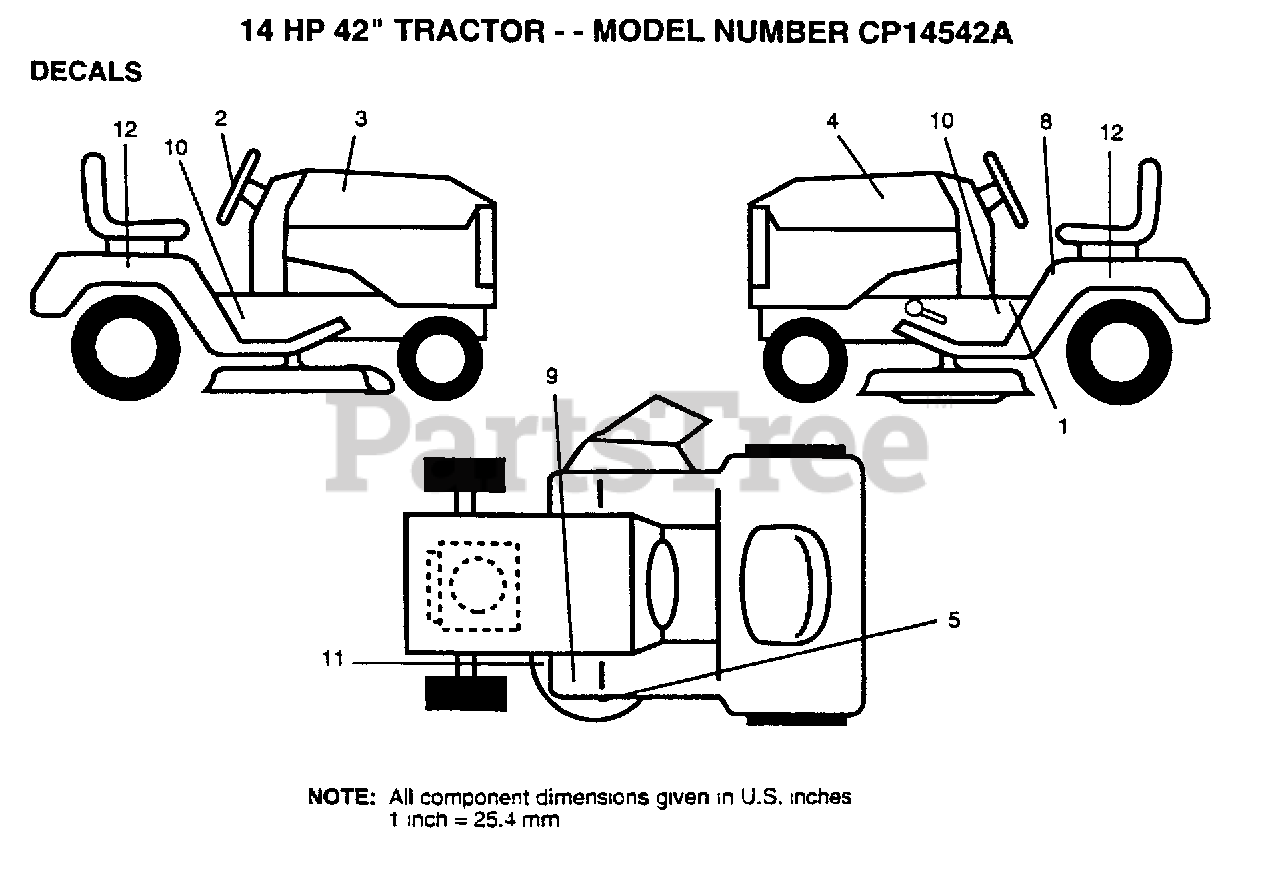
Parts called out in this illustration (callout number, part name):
3	DECAL.HD.RH.CP.
4	DECAL.HD.LH.CP.
8	DECAL
10	CHASSIS DECAL
11	DECAL
12	DECAL.FEND.QUICK.
